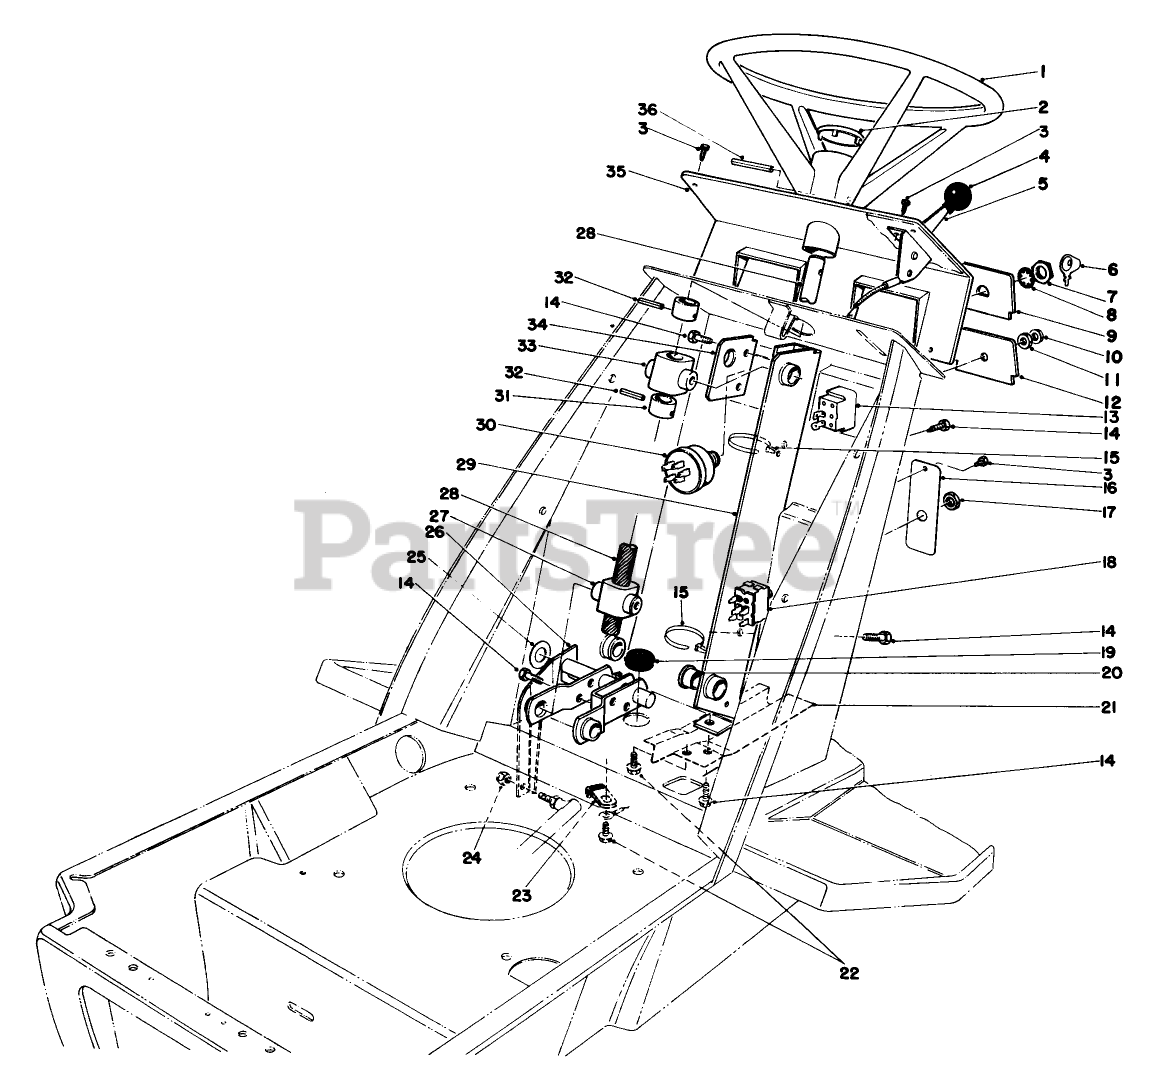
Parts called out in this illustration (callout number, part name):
3	SCREW-HWHTF
4	KNOB-CONTROL
5	THROTTLE CONTROL
7	8-461 Nut
8	WASHER-LOCK
10	Facenut
11	Locknut
13	Light Switch
14	SCREW-THD ROLL, HWH
15	10 Pushmount Tie
19	GROMMET
20	BEARING-FLANGE
22	SCREW-HWH
23	CLIP-FUEL LINE
24	NUT-HEX
28	STEERING SHAFT
30	SWITCH-STARTER
31	STRG SHAFT COLLAR
32	PIN-SPRING
36	PIN-ROLL
